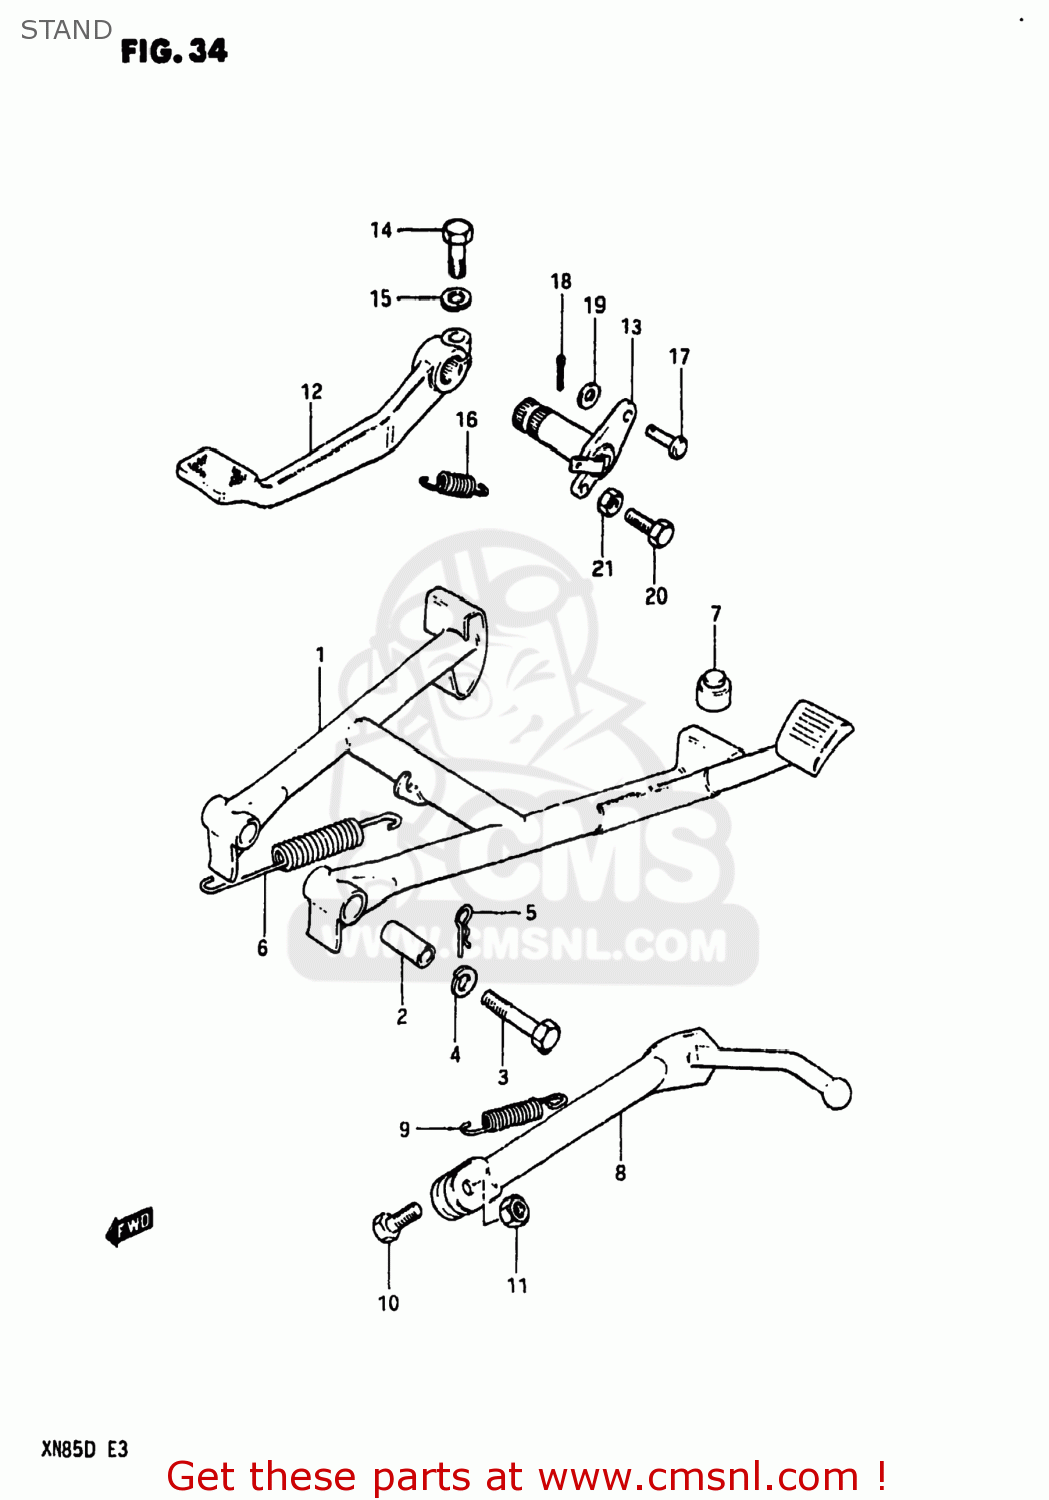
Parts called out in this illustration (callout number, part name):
1	STAND,CENTER
2	SPACER(10X16X38.8)
3	BOLT
4	LOCK WASHER
5	CLIP
6	SPRING
7	CUSHION
8	STAND,SIDE
9	SPRING
10	BOLT L:30
11	NUT
12	PEDAL,BRAKE
13	ARM,BRAKE PEDAL
14	BOLT
15	LOCK WASHER
16	SPRING
17	PIN
18	PIN
19	WASHER
20	BOLT(6X25)
21	NUT
